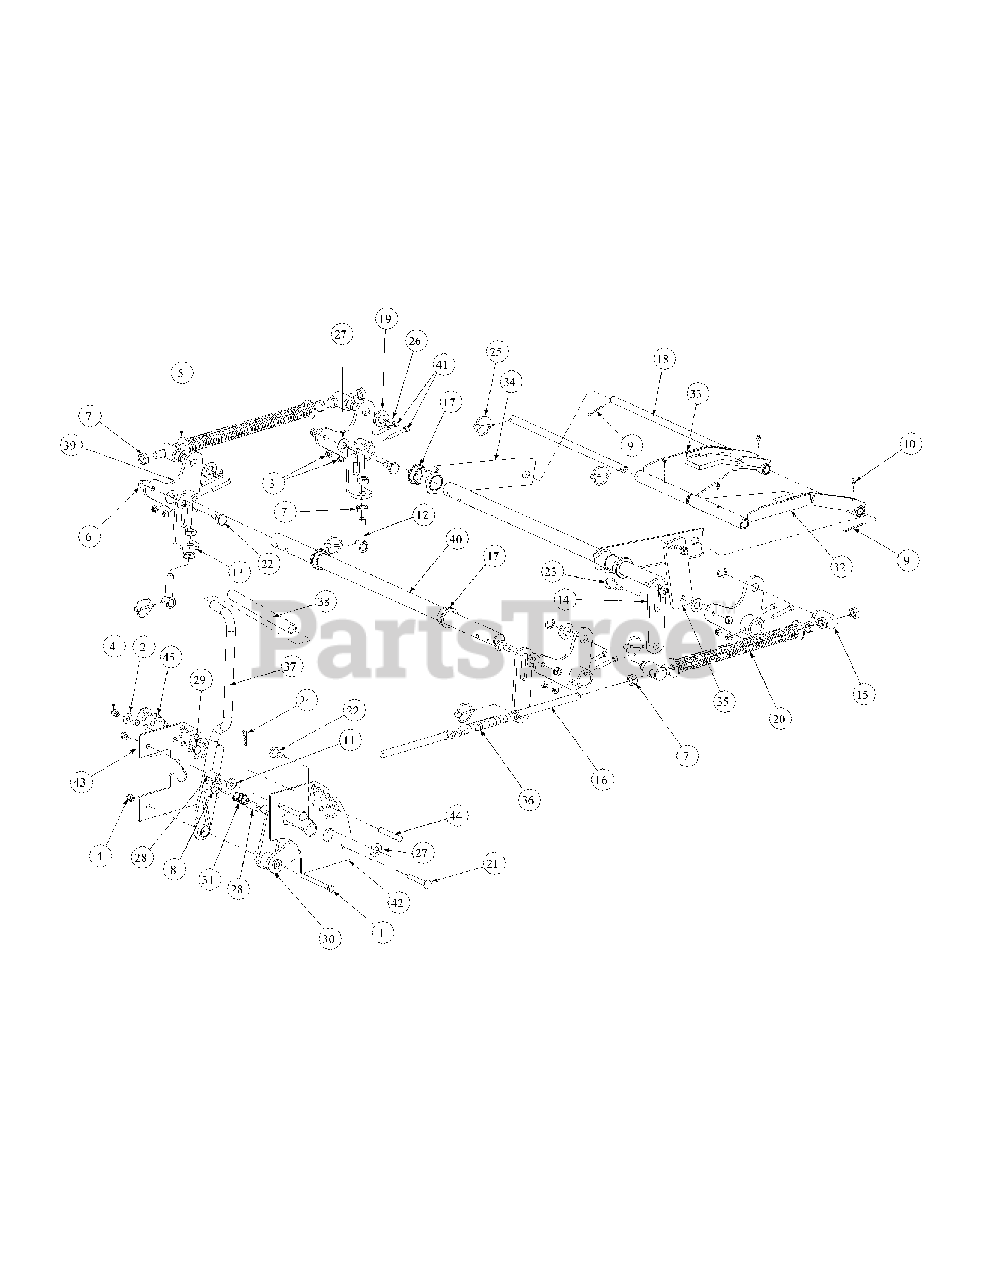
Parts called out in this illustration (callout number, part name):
1	Hex Cap Screw, 3/8-16, 3.75
2	Flat Washer, 3/8
3	Nut, 5/16-18, Nylock
4	Nylock Insert Lock Nut, 3/8-16
5	Flat Washer, 5/8
6	Hex Nut, Flange Lock, 3/8-16
7	Jam Nut, 5/8-11
8	Flat Washer, .06, .776, 1.25
9	Cotter Pin, 3/16 x 1-1
10	Grease Fitting, 1/4-28 x 3/16
11	Idler Washer
12	Eye Bolt, 5/8ID
13	Eye Bolt Mount Link, 5/8 ID
14	Deck Link
15	Ferule Lift
16	Lift Connector Rod
17	Hex Flange Bearing, 1.25 ID
18	Front Lift Link, Rod Mount
19	Spacer, .812 ID x .268 Lg.
20	Lift Compression Spring
21	Carriage Bolt, 3/8-16, 2.75
22	Shoulder Screw, 0.625 OD x .437 Lg.
23	Shoulder Screw, 0.625 OD x .830 Lg.
24	Cotter Pin, .148 x 3.00
25	Linch Pin, 3/16 Dia.
26	Clip, 3/4 Dia.
27	Nylon Flat Washer, 5/8
28	Spacer, .39 ID x .63 OD x 1.442
29	Shoulder Screw,.50 OD x 0.27
30	Lift Pivot Assembly
31	Lift Handle Spring
32	Bearing Lift Brace Assembly, Right Hand
33	Bearing Lift Brace Assembly, Left Hand
34	Front Frame Strut Assembly
35	Lift Link Adjustment
36	Hose, 5/8 ID 13/16 OD, 8" LG
37	Lift Handle Assembly
38	Lift Handle Grip
39	Bellecrank Weldment Assembly
40	Deck Lift Shaft
41	Socket Head Cap Screw, 5/16-18 x 2
42	Outer Lift Index Plate
43	Inner Lift Index Plate
44	Clevis Pin,.438 Dia. x 2.625 Lg.
45	Decal Height Indicator
